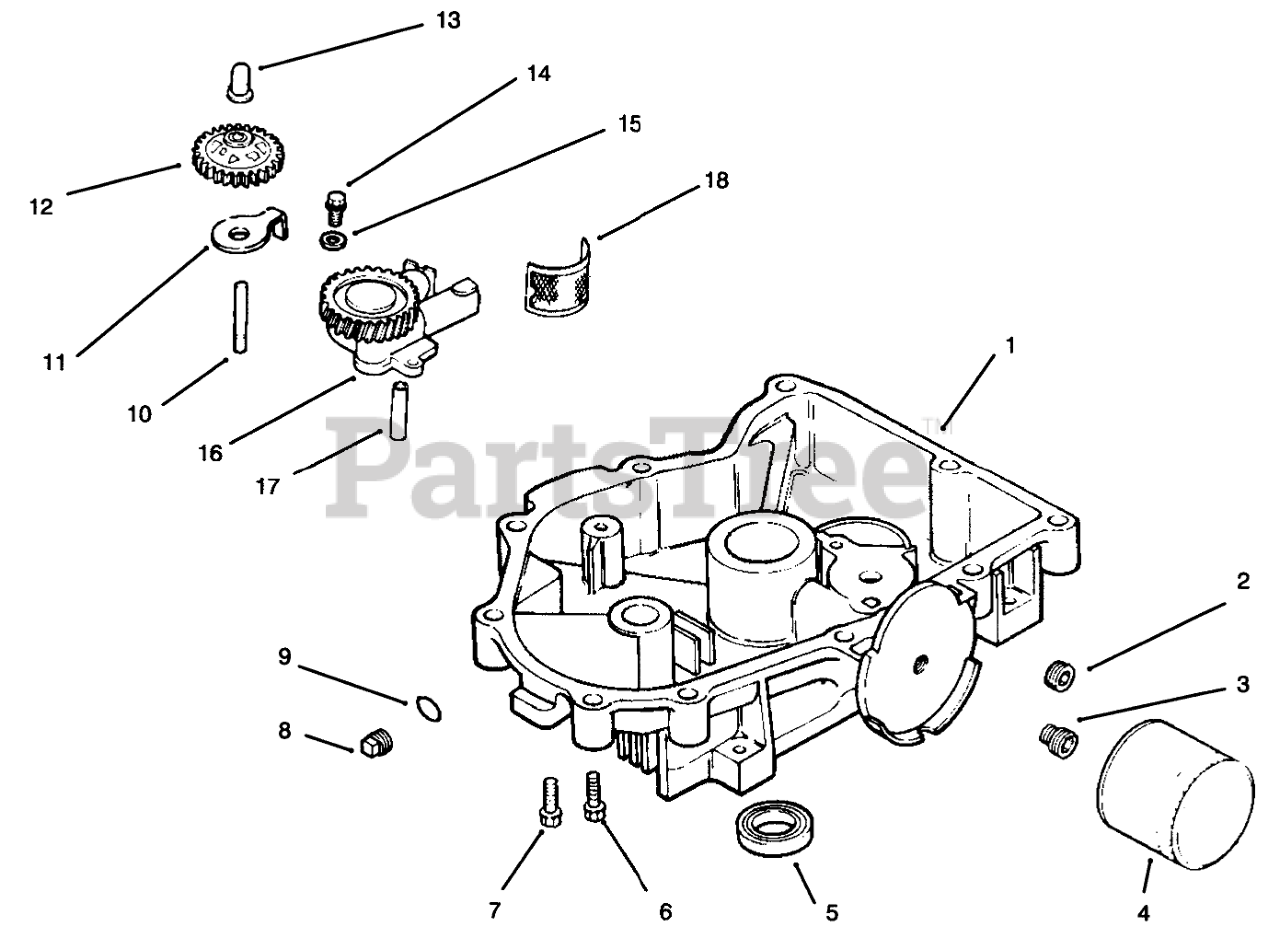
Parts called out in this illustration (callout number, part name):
1	Pan-Oil
2	Plug
3	Nipple-Oil Filter
4	Filter-Oil
5	Seal-Oil
6	Screw
7	Screw
8	Plug
9	O Ring
10	Shaft-Gear, Governor
11	Tab-Locking
12	Kit-Governor Gear (Incl. Ref.#13)
13	Pin-Governor
14	Screw
16	Oil Pump Assembly (Incl. Ref.#17)
17	Tube-Oil Pickup
18	Screen-Oil
